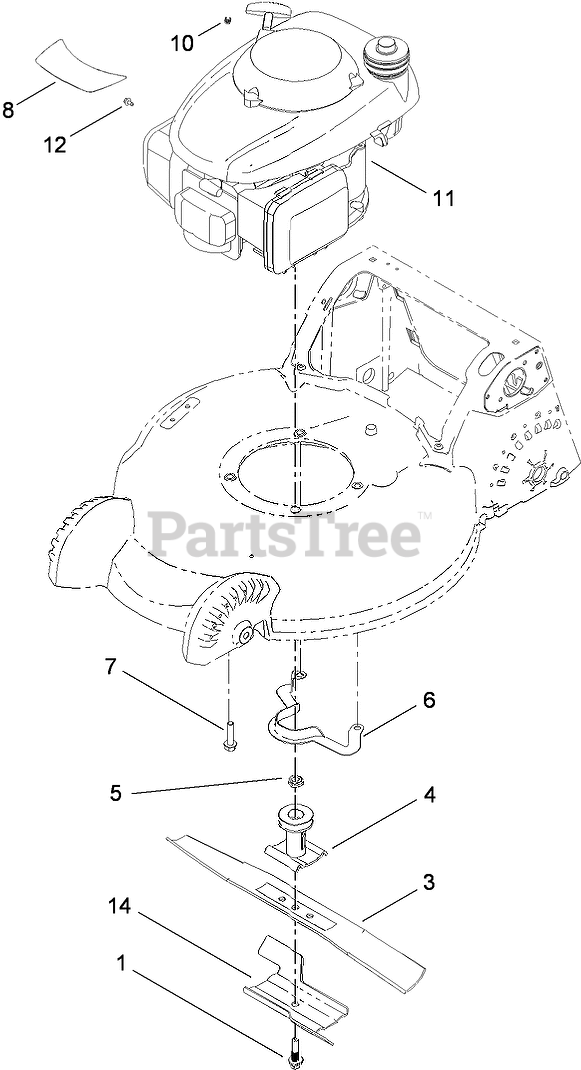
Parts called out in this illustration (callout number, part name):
1	BOLT-BLADE
3	BLADE-21 INCH
4	DRIVER-BLADE
5	Spacer-Driver
6	GUIDE-BELT
7	SCREW-HWH
8	DECAL-HONDA
10	STOP-ROPE
12	SCREW-HWH
14	Accelerator-Blade
